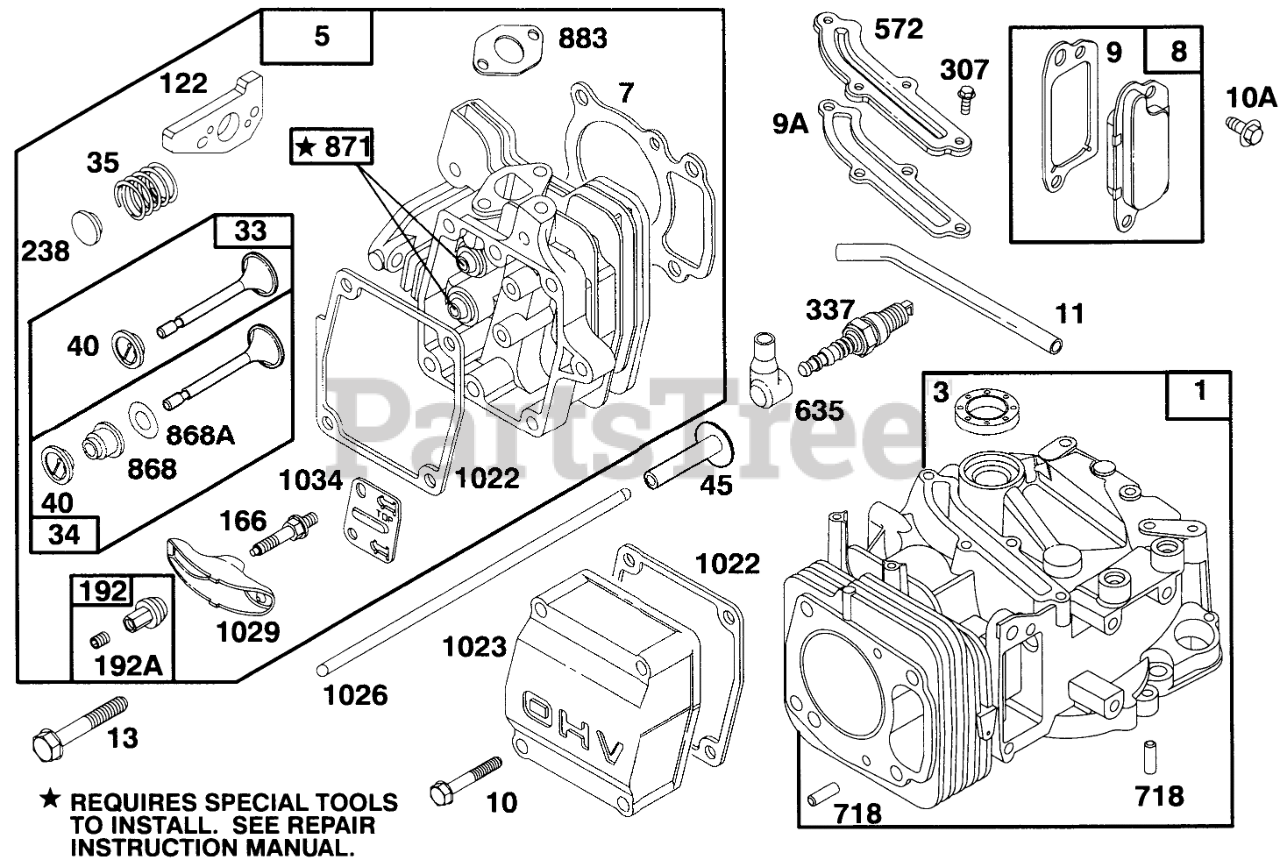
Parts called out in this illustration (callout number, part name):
1	CYLINDER ASSEMBLY
3	SEAL - OIL
5	CYLINDER HEAD
7	CYLINDER HEAD GASKET
8	Breather Assy
9	BREATHER GASKET
9A	GASKET-BREATHER
10	HEX HEAD SCREW
10A	HEX HEAD SCREW
11	TUBE - BREATHER
13	CYLINDER HEAD SCREW
33	EXHAUST VALVE
34	INTAKE VALVE
35	VALVE SPRING
40	SPRING RETAINER
45	VALVE TAPPET
122	ADAPTER ASSEMBLY
166	ROCKER ARM STUD
192	NUT - HEX SPECIAL
192A	SCREW SET
238	VALVE CAP
307	SCREW - SEM
337	PLUG-SPARK
572	BAFFLE - CYCLINDER
635	SPARK PLUG ELBOW
718	DOWEL - SLEEVE
868	SealAssy-Valve
868A	Seal-Valve
871	Bushing-Guide
883	EXHAUST GASKET
1022	ROCKER COVER GASKET
1023	COVER - VALVE
1026	PUSH ROD
1029	ROCKER ARM
1034	PUSH ROD GUIDE
